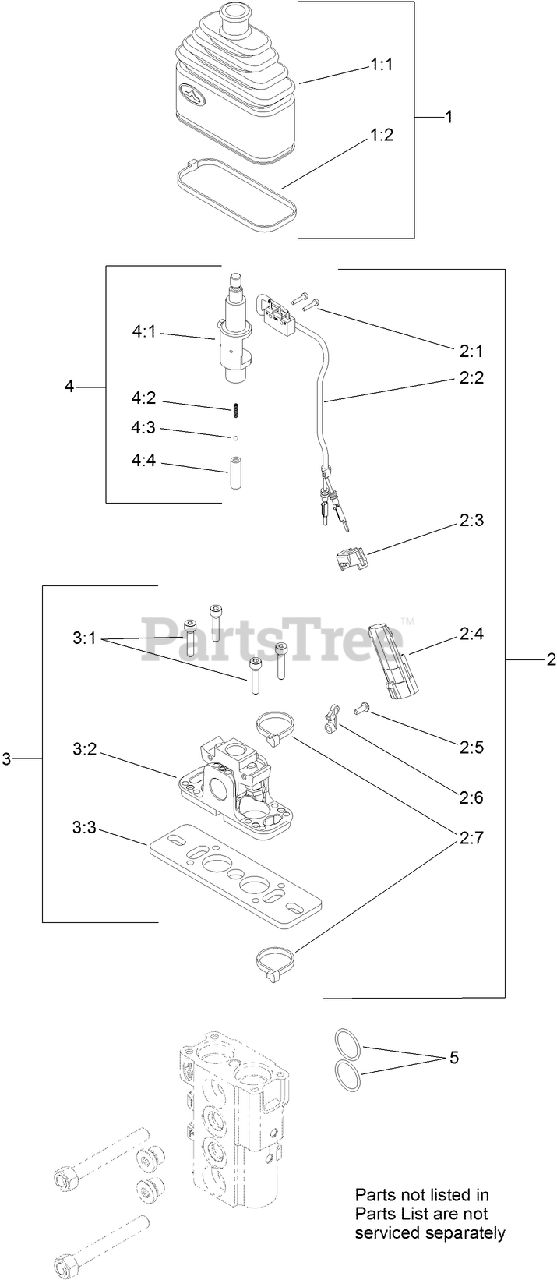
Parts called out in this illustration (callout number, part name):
1	BELLOW KIT
1:1	BELLOW-RUBBER
1:2	TIE-CABLE
2	LIMIT SWITCH KIT
2:1	Screw
2:2	Cable
2:3	FAIRLEAD
2:4	Connector
2:5	Screw
2:6	TIE-WIRE
2:7	TIE-CABLE
3	FULCRUM KIT
3:1	Screw
3:2	SUPPORT KIT
3:3	PLATE-MOUNTING
4	SWITCH HOLDER LEVER KIT
4:1	LEVER-HOLDER, SWITCH
4:2	SPRING-RETURN
4:3	SPHERE
4:4	HOLDER-SPRING
5	O-RING
